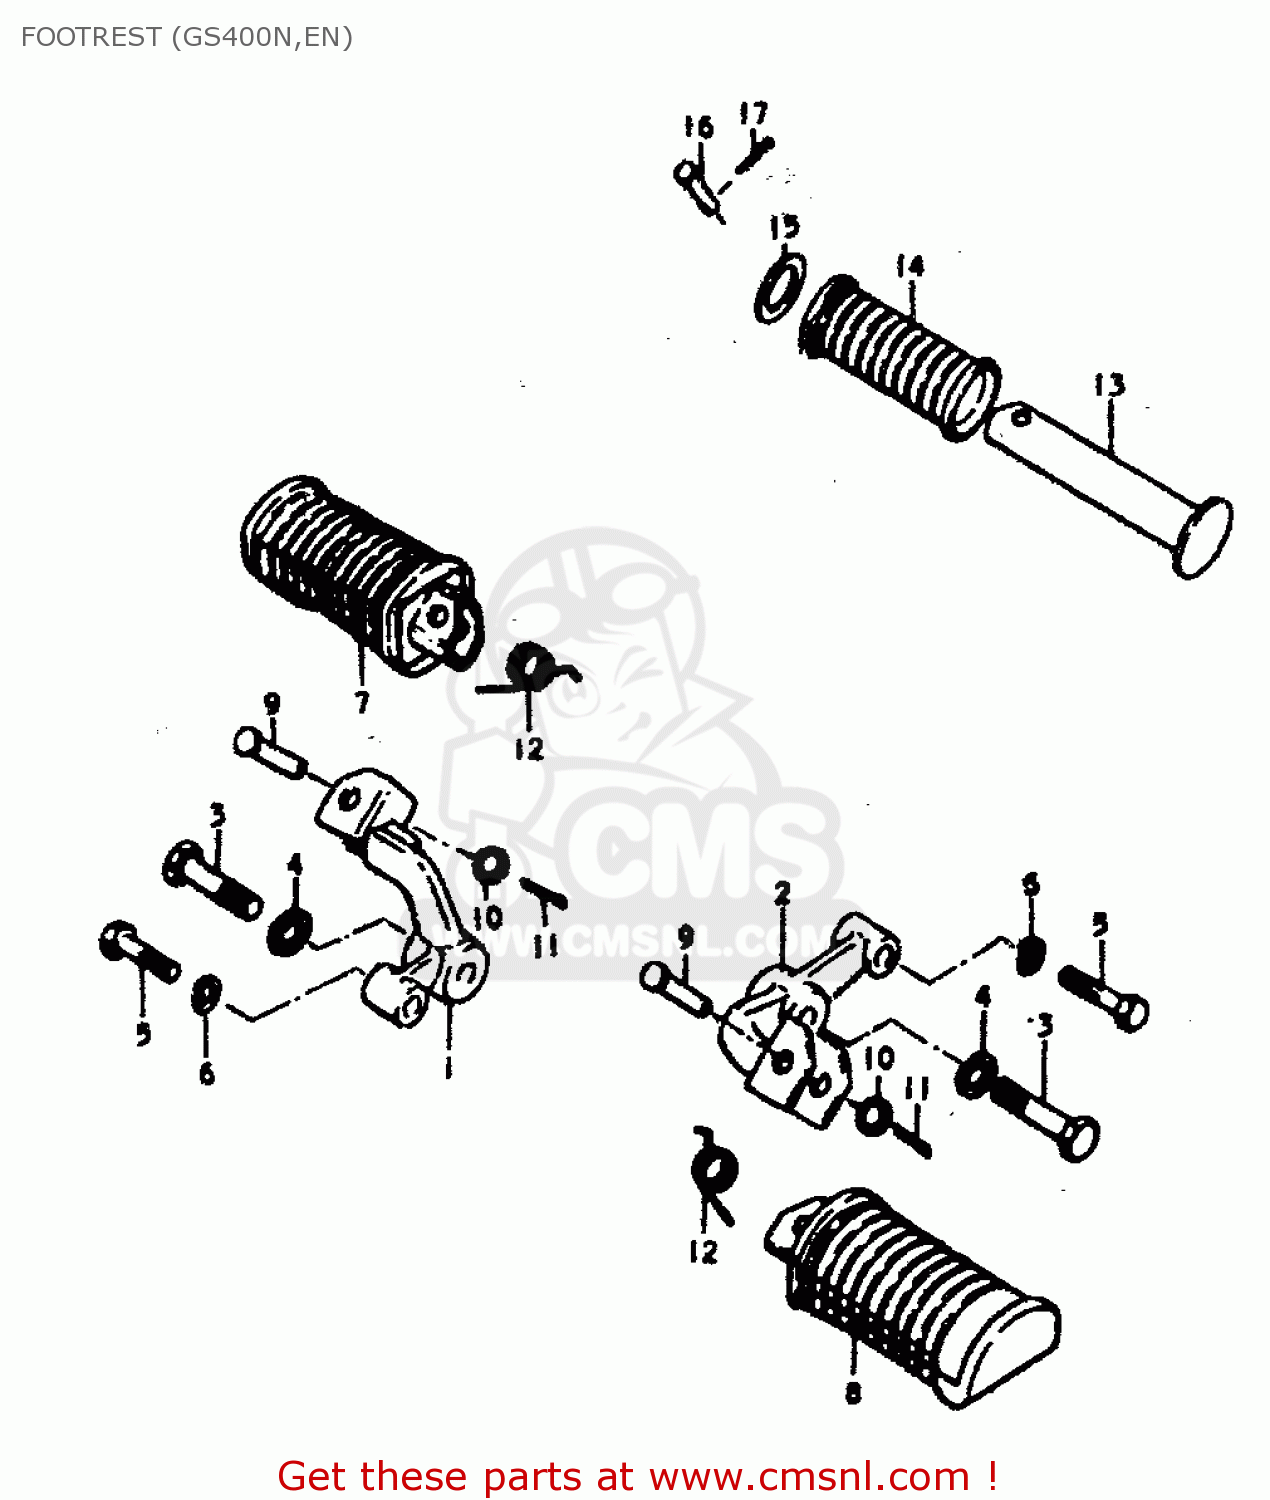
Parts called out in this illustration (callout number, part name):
1	BAR,FRONT FOOTREST
2	BAR,FRONT FOOTREST,LEFT
3	BOLT
4	LOCK WASHER
5	BOLT 8X40
6	LOCK WASHER
7	RUBBER,FRONT FOOTREST
8	FOOTREST
9	PIN
10	WASHER
11	PIN 20X20
12	SPRING
13	BAR,FOOTREST RUBBER
14	RUBBER,PILLION FOOTREST
15	WASHER (19.5X32X2)
16	PIN
17	PIN
